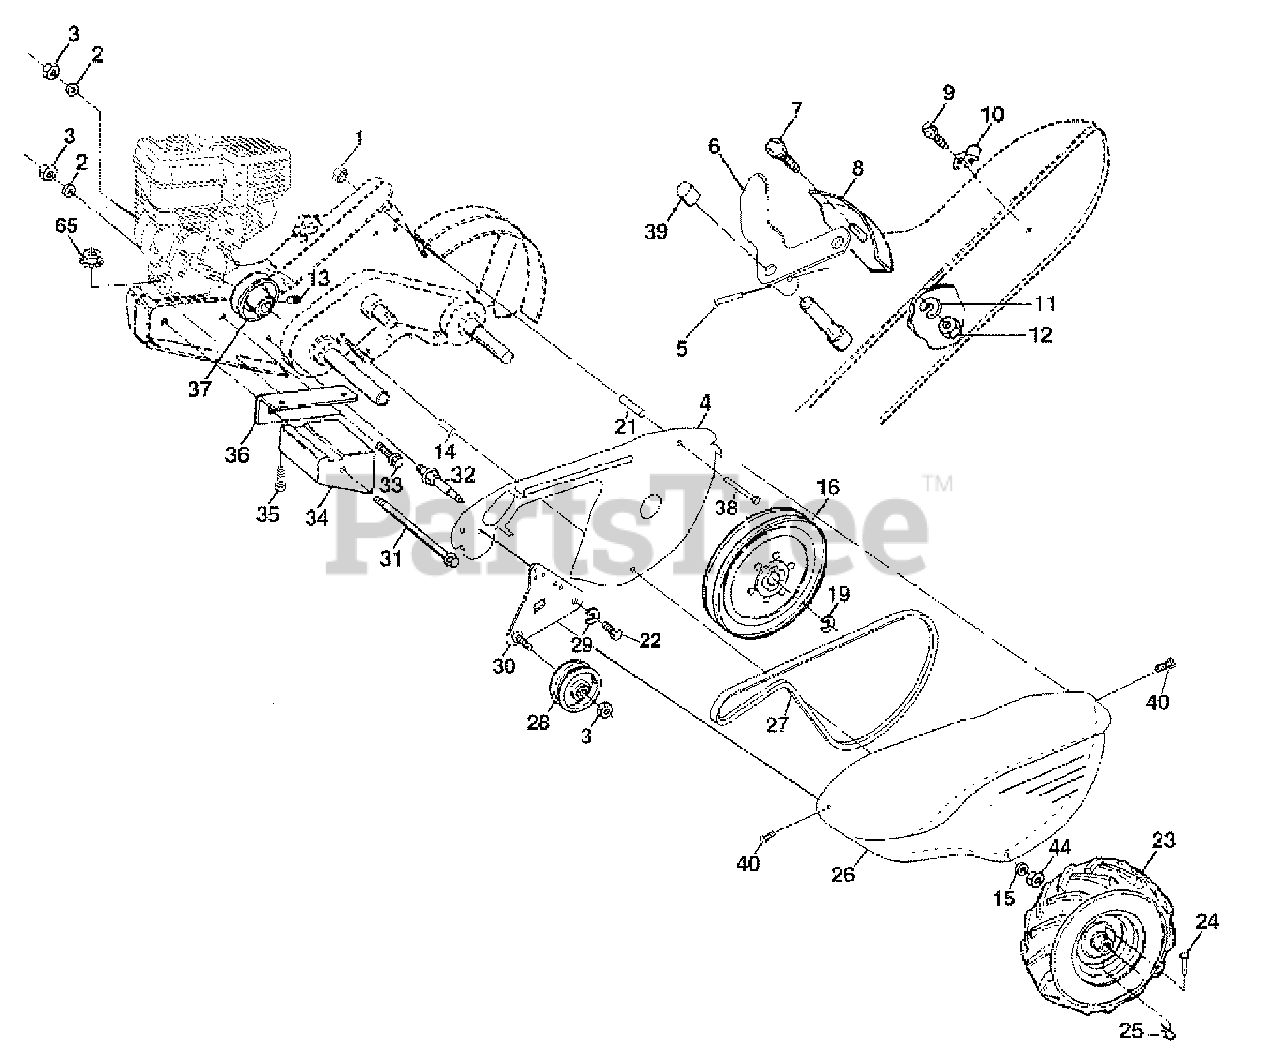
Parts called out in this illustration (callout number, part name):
1	Nut, Keps 5/16-18
2	Washer, Lock 3/8
3	Nut, Hex 3/8-16
4	Shield, Inner, Belt Guard
5	Pin Spirol Flared
6	Lever, Shift
7	Bolt, Carriage 1/4-20 x 1/2 Gr. 5
8	Plate, Shift Indicator
9	Screw, Hex, Washer Head, Slotted #10-24x1/2
10	Clip
11	Washer, Lock 1/4
12	Nut, Hex 1/4-20
13	Screw, Set, Hex 5/16-18 x 3/8
14	Spacer, Split 0.327 x 0.42 x 1.220
15	Washer 11/32 x 11/16x 16 Ga.
16	Sheave, Transmission
19	Ring, Retainer
21	Spacer, Split 0.327 x 0.42 x 2.09
22	Bolt Hex 5/16-24x1/2
23	Tire
23	Rim
23	Tire Valve
24	Rivet, Drilled
25	Clip, Hairpin
26	Guard, Belt
27	Belt, V
28	Pulley, Idier
29	Ring, Klip
30	Bracket, Idier
31	Bolt, Hex 5/16-16x12
32	Shaft, Idler Arm
33	Bolt, Hex 3/8-16 x 1
34	Counterweight, L. H,
35	Bolt, Hex 5/16-18x1-1/2
36	Bracket, Reinforcement, L. H.
37	Sheave, Engine
38	Bolt, Hex 5/16-18x2-3/4
39	Cap, Plunger
40	Screw, Hex Wsh Sit #10-24x .50
44	Nut, Lock 5/16-18
65	Nut, Lock Hex Flange
